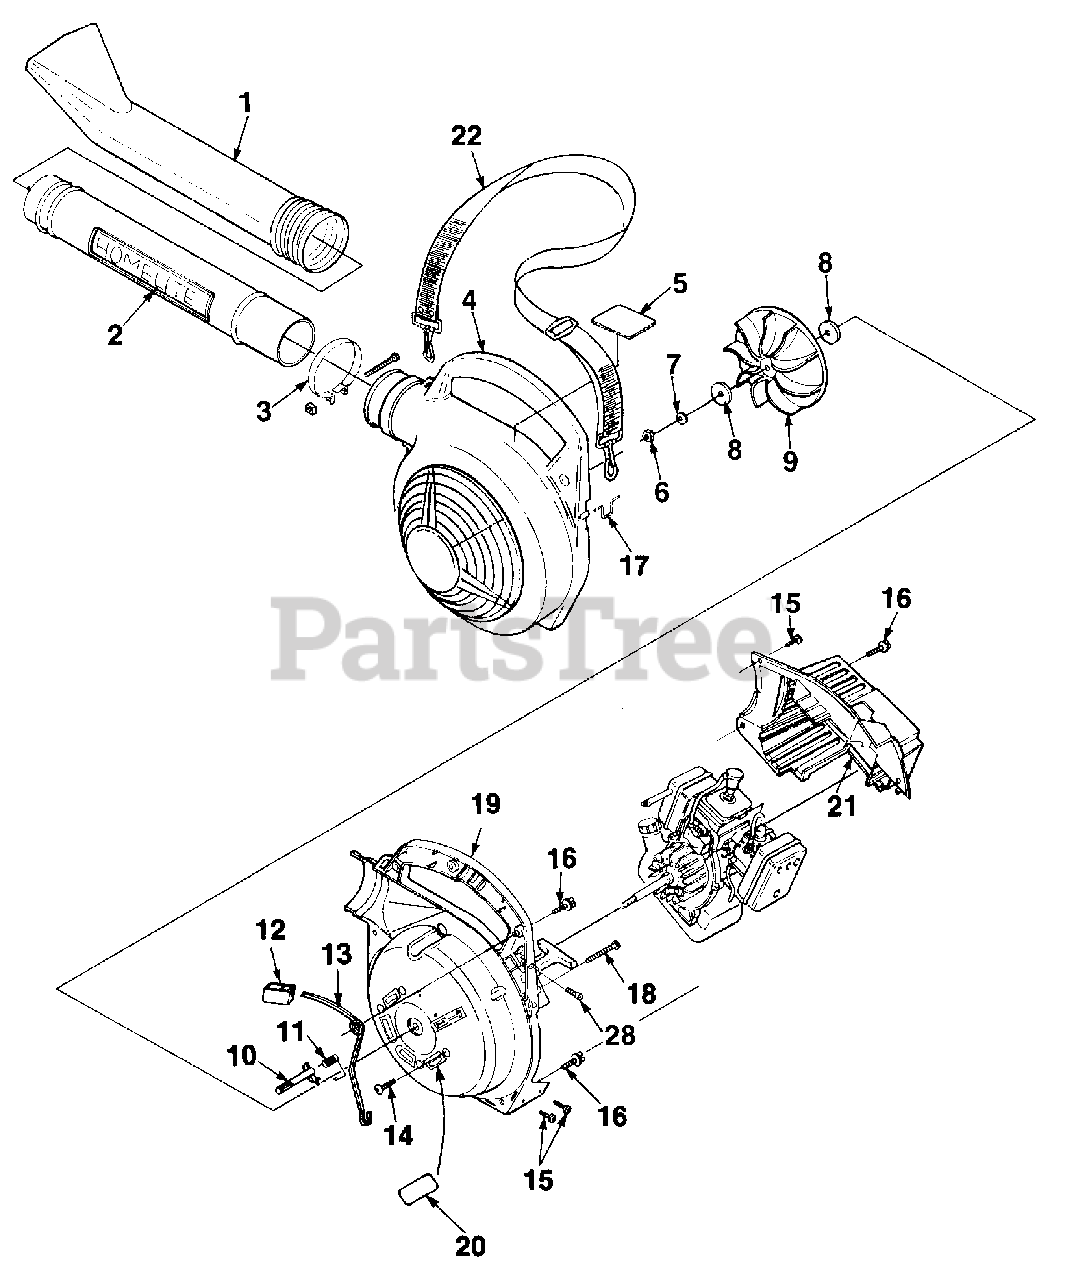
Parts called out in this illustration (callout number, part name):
1	NOZZLE- Sweeper
2	TUBE w/DECAL
3	CLAMP
4	HOUSING- Volute (outer)
5	DECAL- Warning
6	NUT- Hex 5/16-24
7	WASHER- Belleville #10
8	WASHER- Flat
9	FAN- Blower
10	LATCH- Throttle
11	SPRING- Throttle latch
12	TRIGGER- Throttle
13	LEVER- Throttle
14	SCREW- Thd Forming
15	SCREW- Tapping pan #8 x 1/2
16	SCREW- Thd forming #10 x 3/4
17	LOOP- Wire
18	SCREW- Hex hd. #10 x 15/8
19	HOUSING- Volute (inner)
20	KIT- Sealing
21	SHROUD
22	STRAP- Shoulder (Acc.)
